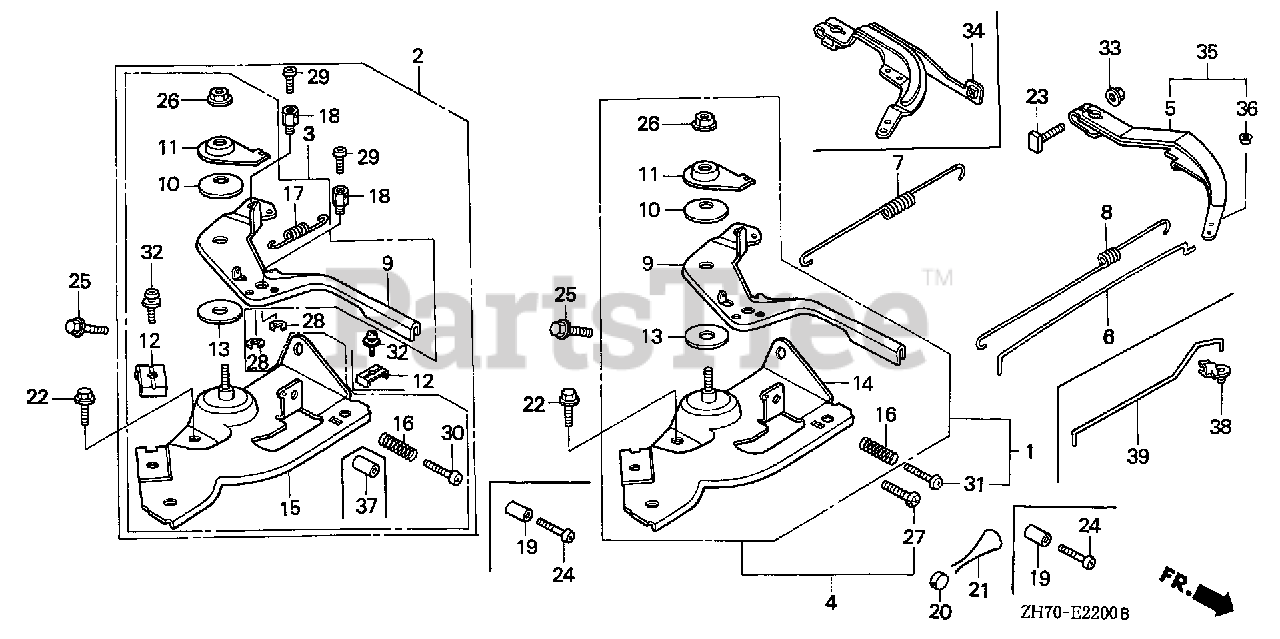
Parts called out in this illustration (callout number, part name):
1	CONTROL ASSY.
5	ARM, GOVERNOR
6	ROD, GOVERNOR
7	SPRING, GOVERNOR
8	SPRING, THROTTLE RETURN
9	LEVER, CONTROL
10	SPRING, LEVER
11	WASHER, CONTROL LEVER
13	SPACER, CONTROL LEVER
14	BASE, CONTROL
16	SPRING, CONTROL ADJUSTING
22	BOLT, FLANGE (6X12) (CT200)
23	BOLT, GOVERNOR ARM
25	BOLT, FLANGE (6X20) (CT200)
26	NUT, SELF-LOCK (6MM)
31	SCREW, PAN (5X25)
31	SCREW, PAN (5X28)
33	NUT, FLANGE (6MM)
